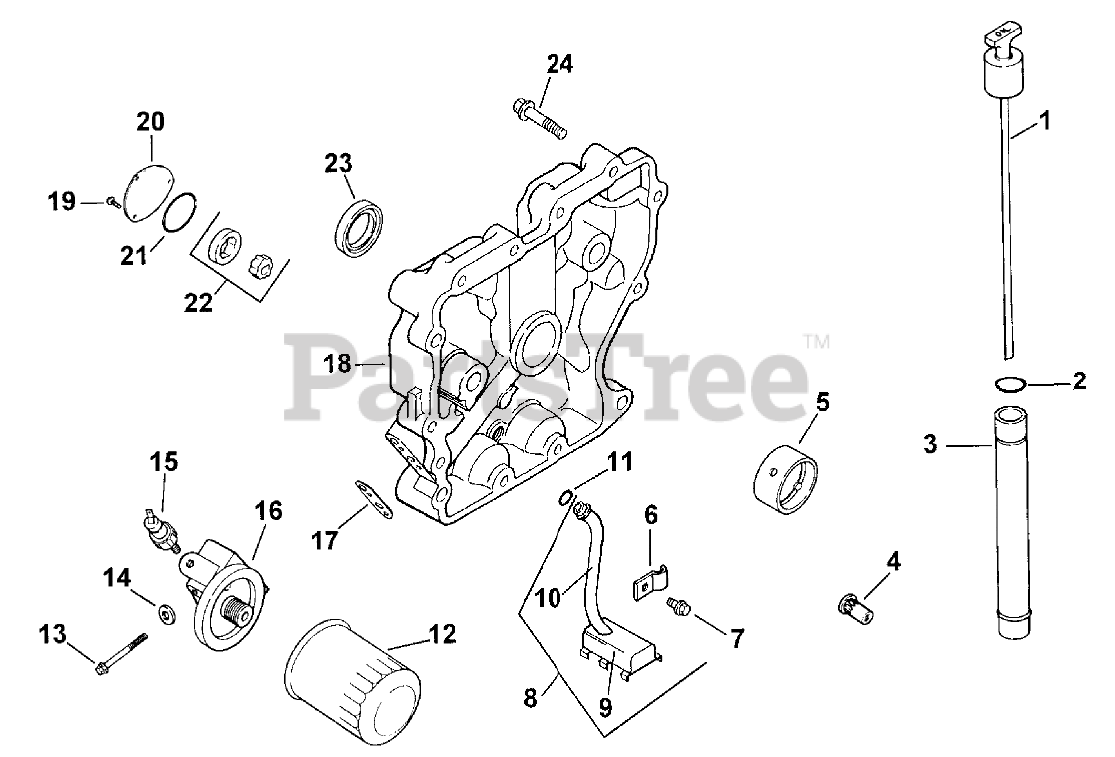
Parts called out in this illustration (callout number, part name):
1	Dipstick
2	O-Ring
3	Tube, oil fill
4	Valve-Oil Pressure
5	Bearing, crankshaft
6	Clip
7	Screw-HF
8	Kit, oil pick-up (Includes 9,10)
9	Pick-up, oil screen
10	Tubing, oil pick-up
11	O-Ring, oil pick-up
12	Filter-Oil
13	Screw, hex. flange M6x1.0x60
14	Washer
15	Swutch, oil pressure
16	Adapter, oil filter
17	Gasket, oil filter adapter
18	Plate, closure Asm (Includes 4, 5, 19-22)
19	Screw-HF
20	Cover, oil pump
21	O-Ring, oil pump cover
22	Pump-Oil
23	Seal-Crankshaft
24	Screw
